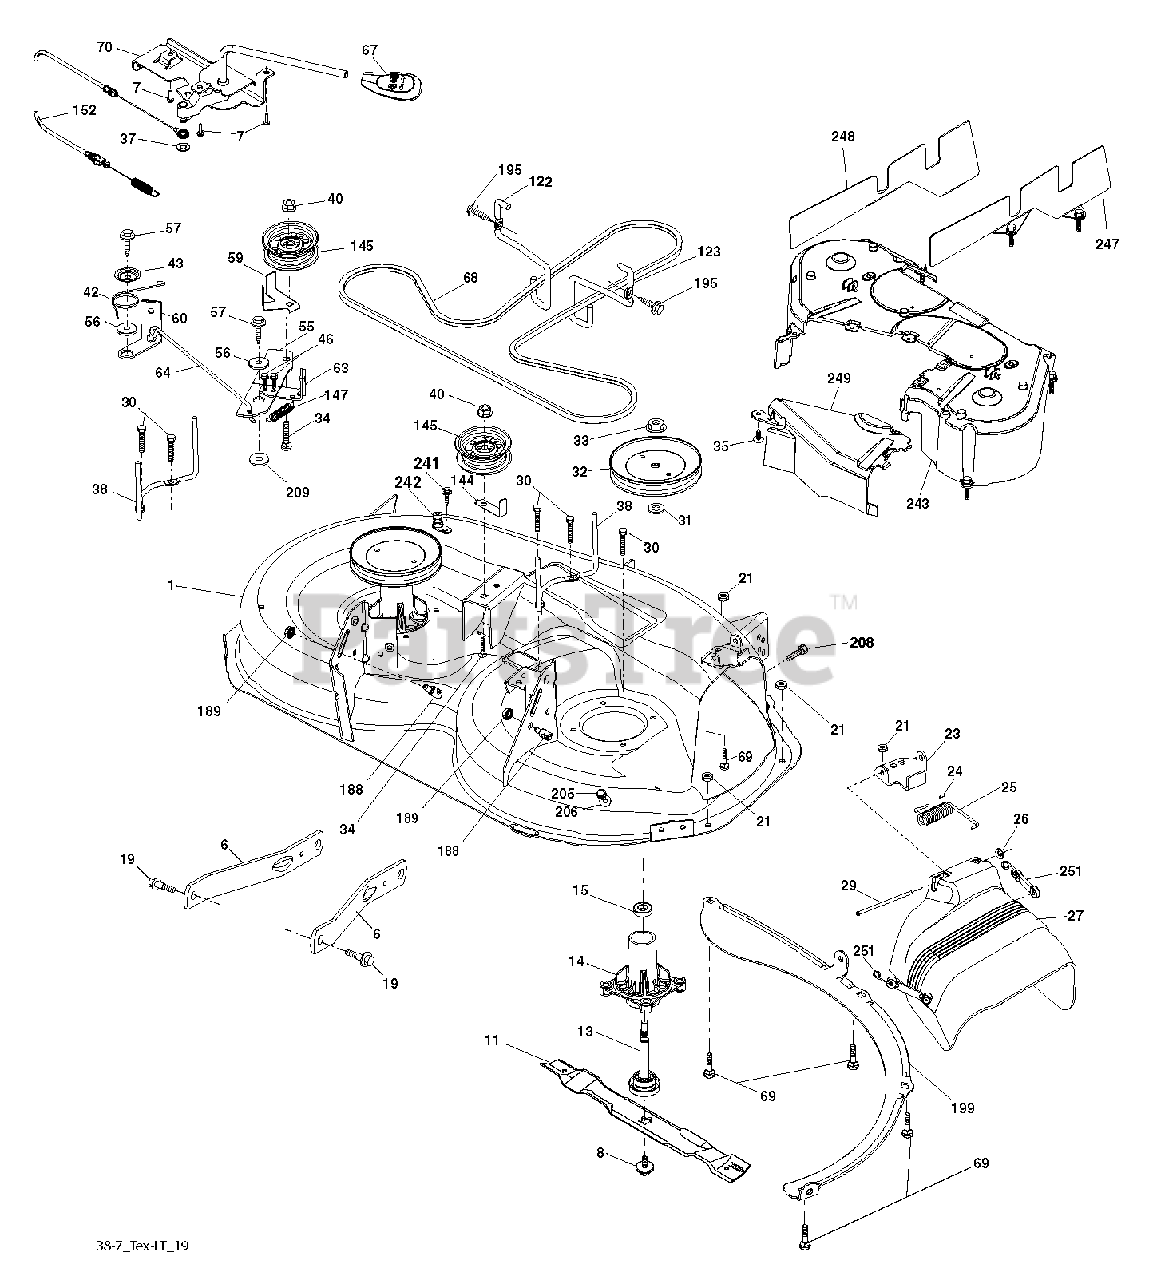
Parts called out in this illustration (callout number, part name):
6	ARM.SUSPENSION.MOWER.R
7	SCREW.#10 X 0.750.BOS THREAD
8	BOLT.WASHER.ASM.7/16-2
11	BLADE 38" PREMIUM
13	SHAFT.ASM.MDRL.N/GREASE.38
14	HOUSING MANDREL
19	BOLT.SHOULDER
21	LOCKNUT
23	BRKT.DEFLECTOR.38"2005+
24	CAP-SLEEVE LT
25	SPRING.TORSION.DEFLECT
26	NUT PUSH M
29	ROD.HINGE
30	SCREW, WASHER HEAD
31	WASHER.SPACER.MANDREL
32	PULLEY.MANDREL.5.0.PD.38"
33	NUT.FLANGE.LOCK.TOP
34	BOLT.3/8-16X1.50
35	FASTENER.XMAS.TREE
38	KEEPER BELT LH MANDREL
40	NUT LOCK FLG 3/8-16 UNC
42	SPRING.TORSION.BRAKE
43	SRPING.TORSION.RETAINE
46	SCREW.1/4-20X5/8
55	IDLER.ARM
56	SPACER.RETAINER
57	SCREW 3/8-16X1
59	GUARD, BELT
60	ARM BRAKE MOWER RH 38"
63	ARM BRAKE MOWER RH
64	LINK BRAKE
67	HANDLE.CLUTCH.CABLE.LT
69	BOLT
70	CLUTCH.ASM.MANUAL.LT.PRED
122	KEEPER BELT ENGINE LH
123	KEEPER BELT RH
144	KEEPER BELT
145	PULLEY.IDLER.48"PRIMARY
147	SPRING RETURN
152	CABLE.CLUTCH.MANUAL.
188	STUD.FASTNER.W/ANTI-ROTATE
189	NUT LOCK HEX FLANGE 5/16-18
195	SCREW, 3/8-16X3/4
199	BAFFLE VORTEX
205	SCREW
208	SCREW 3/8-16X1/2
209	WASHER 12/32X2X10GA
242	PORT.WASHOUT
